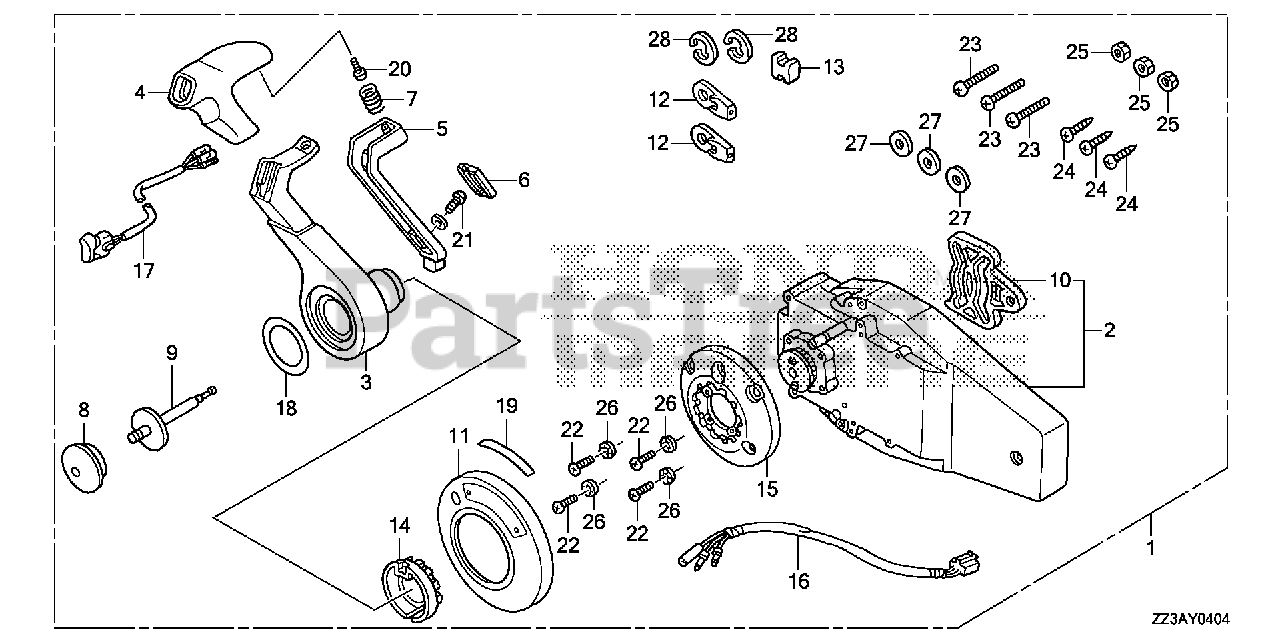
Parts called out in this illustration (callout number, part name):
1	BOX KIT, REMOTE CONTROL (FLUSH MOUNT)(R)
2	HOUSING ASSY., R. (INNER) (FLUSH MOUNT)
3	HANDLE, REMOTE CONTROL
4	COVER, GRIP
5	ARM, NEUTRAL LOCK
6	COVER, LOCK ARM
7	SPRING, NEUTRAL LOCK ARM
8	BUTTON, THROTTLE
9	SHAFT, THROTTLE BUTTON
10	PLATE, DWELL
11	COVER ASSY.
12	TERMINAL, CABLE
13	SPACER, CABLE CLAMP
14	HOLDER, NEUTRAL LOCK
15	BASE
16	SUB-HARNESS ASSY., POWER TRIM-TILT (C)
17	SWITCH ASSY., POWER TRIM-TILT (C)
18	MARK, HANDLE FLUSH MOUNT
19	MARK, FLUSH MOUNT
20	SCREW, PAN (5X16)
21	SCREW, TRUSS (4X12)
22	SCREW, PAN (5X30)
23	SCREW, PAN (6X35)
24	SCREW, TAPPING (6X30)
25	NUT, HEX. (6MM)
26	WASHER, LOCK (5MM)
27	WASHER, PLAIN (6MM)
28	E-RING (6MM)
